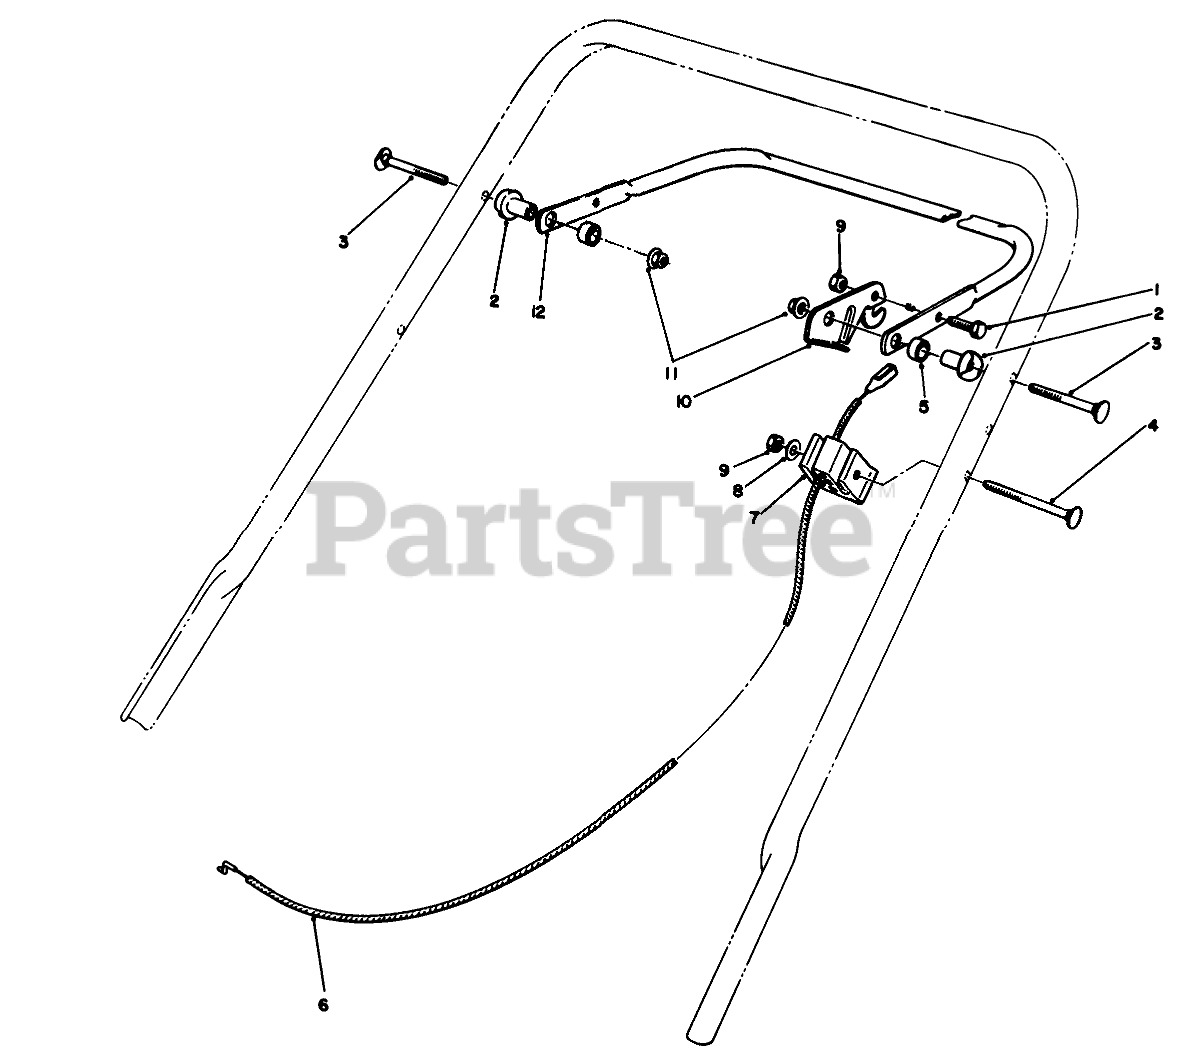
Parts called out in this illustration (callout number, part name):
1	SCREW-HH
2	SPACER-SUPPORT
3	5/16-18 X 2 HNDLE SCREW
4	HANDLE SCREW
5	SPACER-NYLON
6	BRAKE CONTROL
7	SUPPORT-CABLE
8	WASHER-FLAT
9	NUT-LOCK, NI
10	LEVER-CONTROL
11	NUT-LOCK, NI
12	Bar-Control
